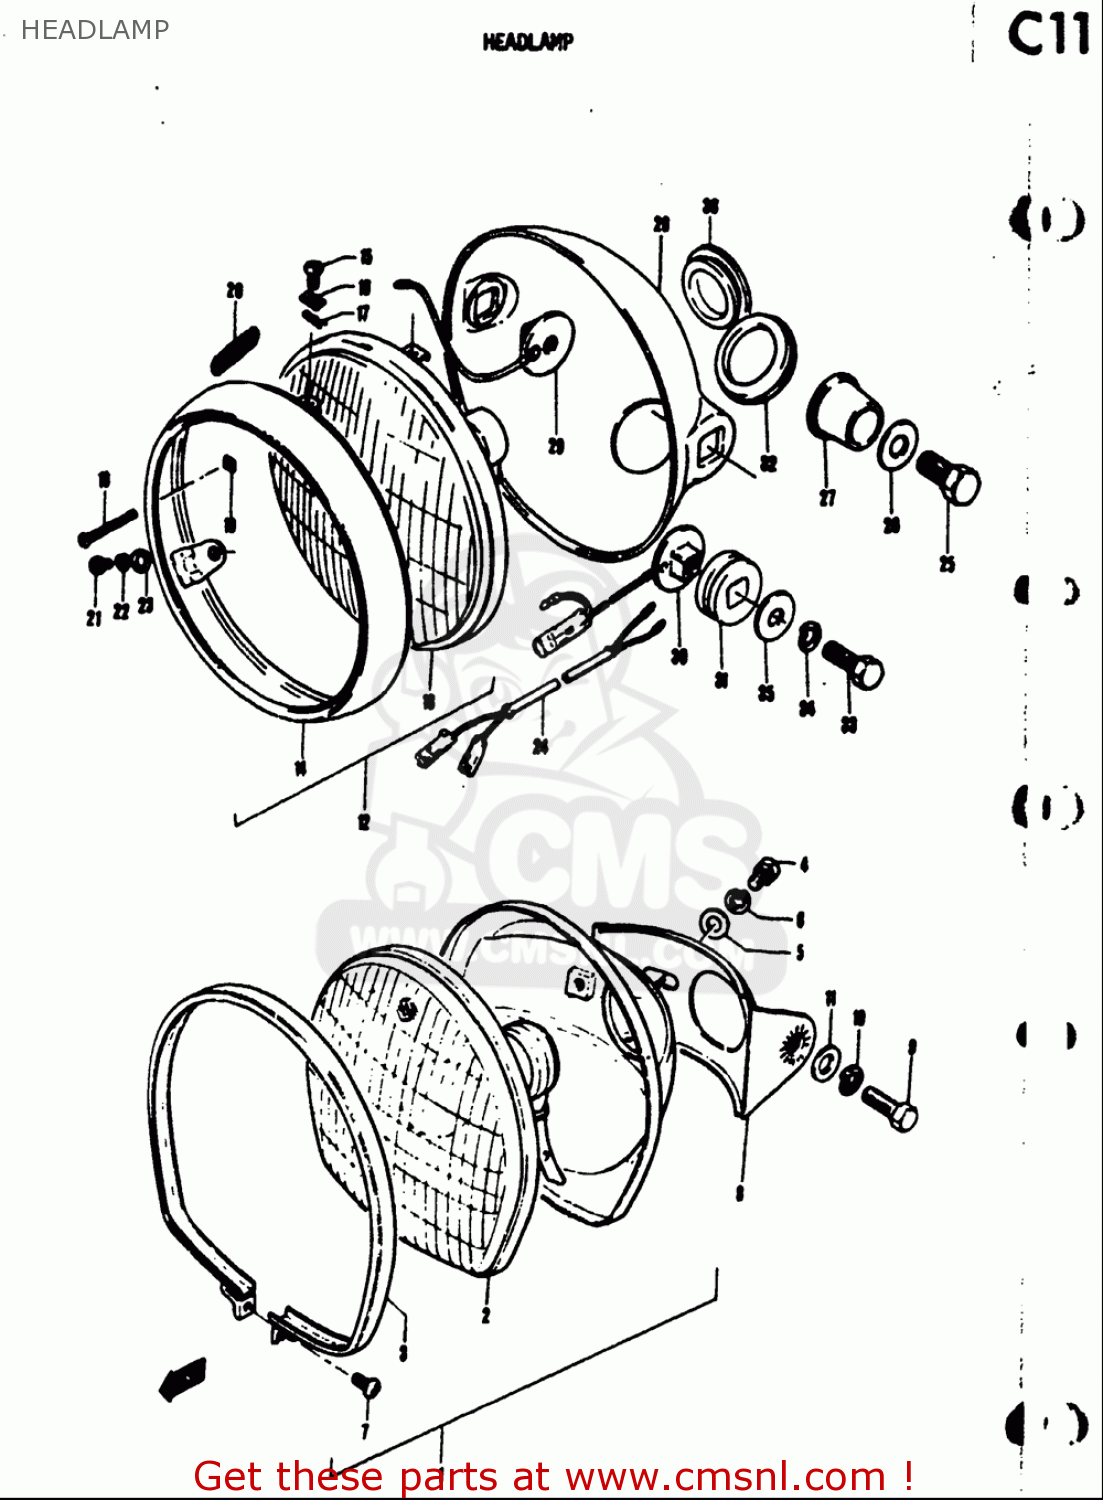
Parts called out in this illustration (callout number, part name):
4	BOLT
5	WASHER
6	WASHER,LOCK
7	SCREW
9	BOLT
10	WASHER,LOCK
11	WASHER
15	SCREW,LENS
16	NUT
18	SCREW,HEADLAMP ADJUST
19	NUT,HEADLAMP ADJUSTER
20	SPRING,HEADLAMP ADJUST
21	SCREW
22	WASHER,LOCK
23	WASHER
25	BOLT
26	WASHER
27	COVER,FRONT TURN SIGNAL BRACKET
28	HOUSING,HEADLAMP
31	CUSHION,HEADLAMP HOUSING
33	BOLT
34	WASHER,LOCK
35	WASHER
36	CAP
